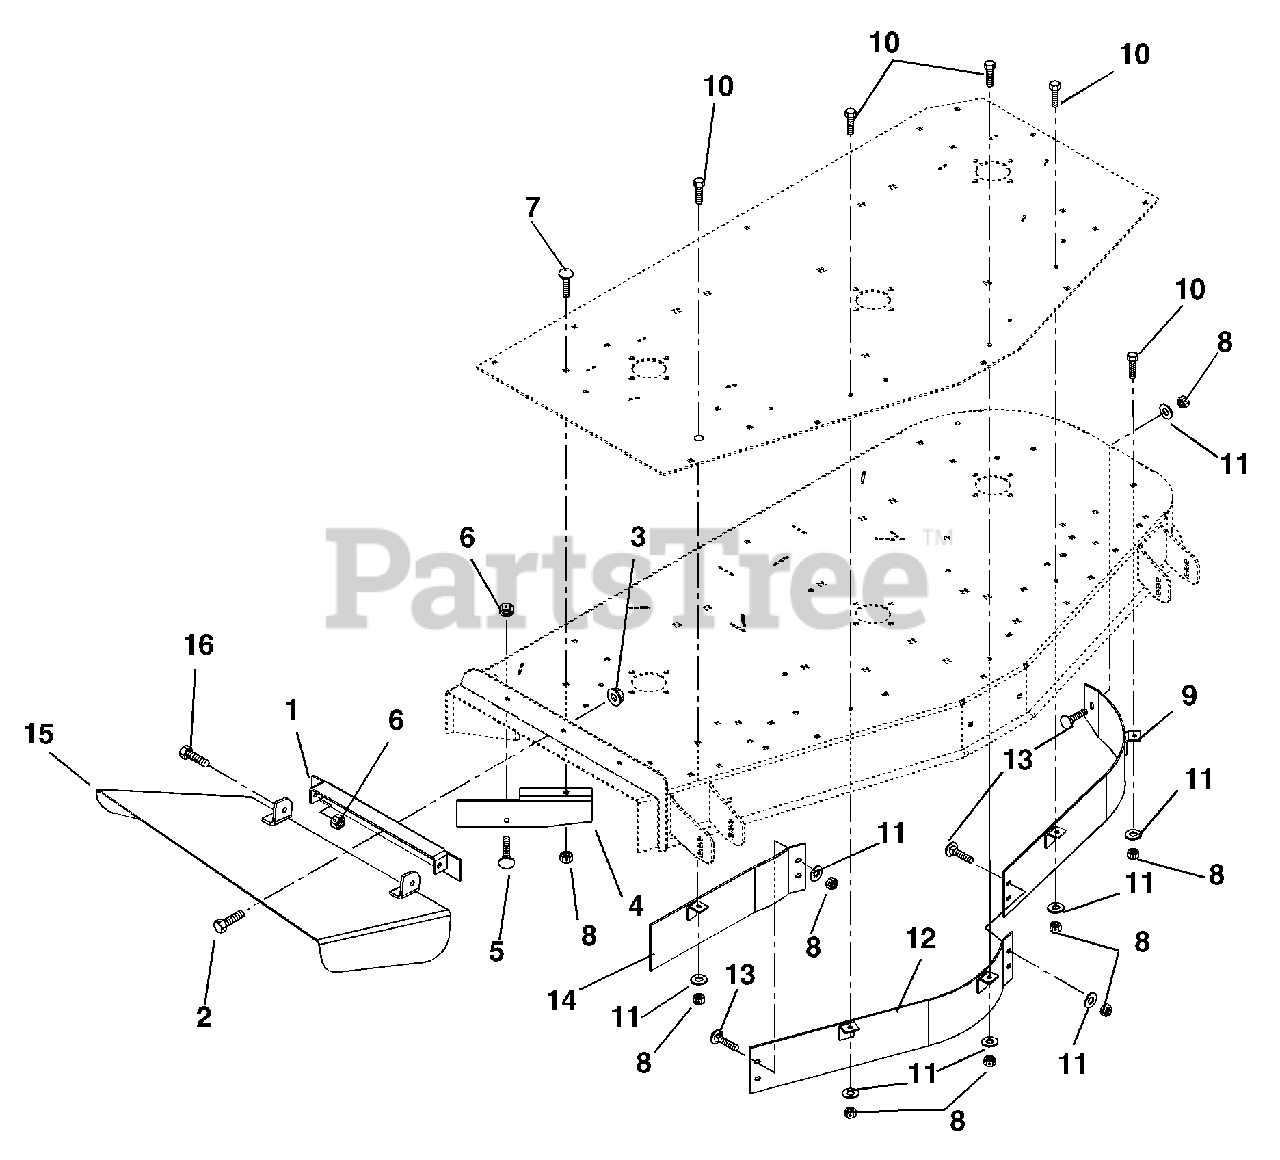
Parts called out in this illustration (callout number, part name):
1	Weldment, Discharge Chute Bracket
2	Bolt-Hex .38-16 x 1.00 Grade 5
3	Nut-Locking-Flange .38-16
4	Deflector, 60
5	Bolt-Round Head Square Neck .38-16 x 1.00 Grade 2
6	Nut-Locking-Center .38-16
7	Bolt-Round Head Square Neck .31-18 x 1.00 Grade 5
8	Nut-Locking-Nylon .31-18
9	Weldment, 60" Left Hand Baffle-Upper
10	Bolt-Hex .31-18 x 1.00 Grade 5
11	Washer-Flat-Steel .312 x .734 x .065
12	Weldment, 60" Center Baffle-Up
13	Bolt-Round Head Square Neck .31-18 x .75 Grade 5
14	Weldment, 60" Right Hand Baffle-Upper
15	Weldment, Discharge Chute 60"
16	Bolt-Hex .38-16 x 1.00 Grade 5
17	60" Discharge Cover
18	60" Mulch Kit
